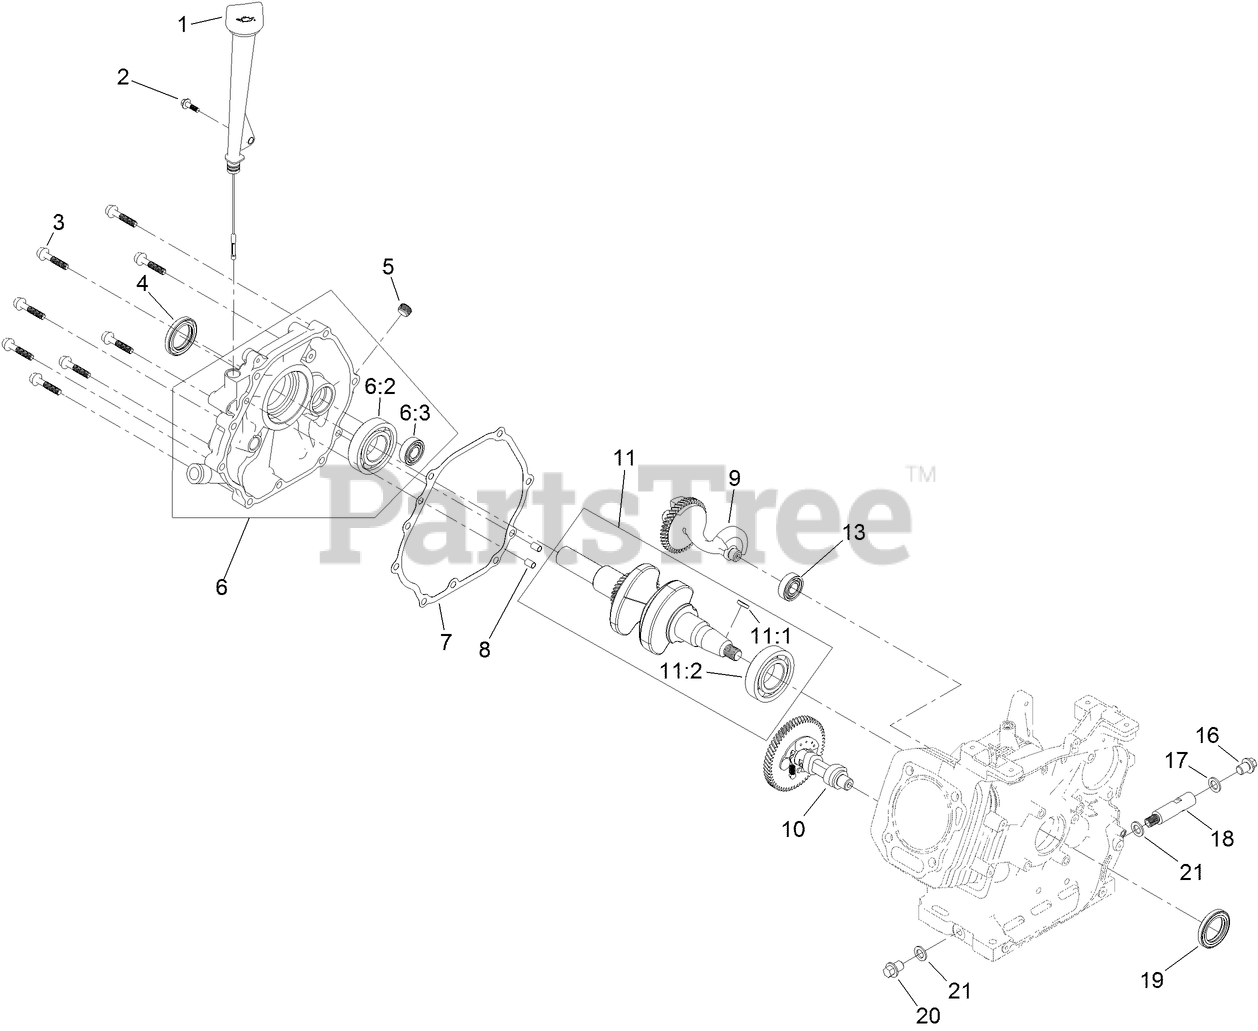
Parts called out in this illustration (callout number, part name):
1	OIL FILL ASM
2	SCREW-HHF
3	SCREW-HHF
4	SEAL-OIL
5	PLUG-DRAIN
6	CRANKCASE COVER ASM
6:2	BEARING-BALL
6:3	BEARING-BALL
7	GASKET-COVER, CASE
8	PIN-DOWEL
9	SHAFT-BALANCE
10	CAMSHAFT ASM
11	CRANKSHAFT ASM
11:1	KEY-WOODRUFF
11:2	BEARING-BALL
13	BEARING-BALL
16	SCREW-HHF
17	WASHER-PLAIN
18	TUBE-DRAIN, OIL
19	SEAL-OIL
20	SCREW-HHF
21	WASHER-PLAIN
